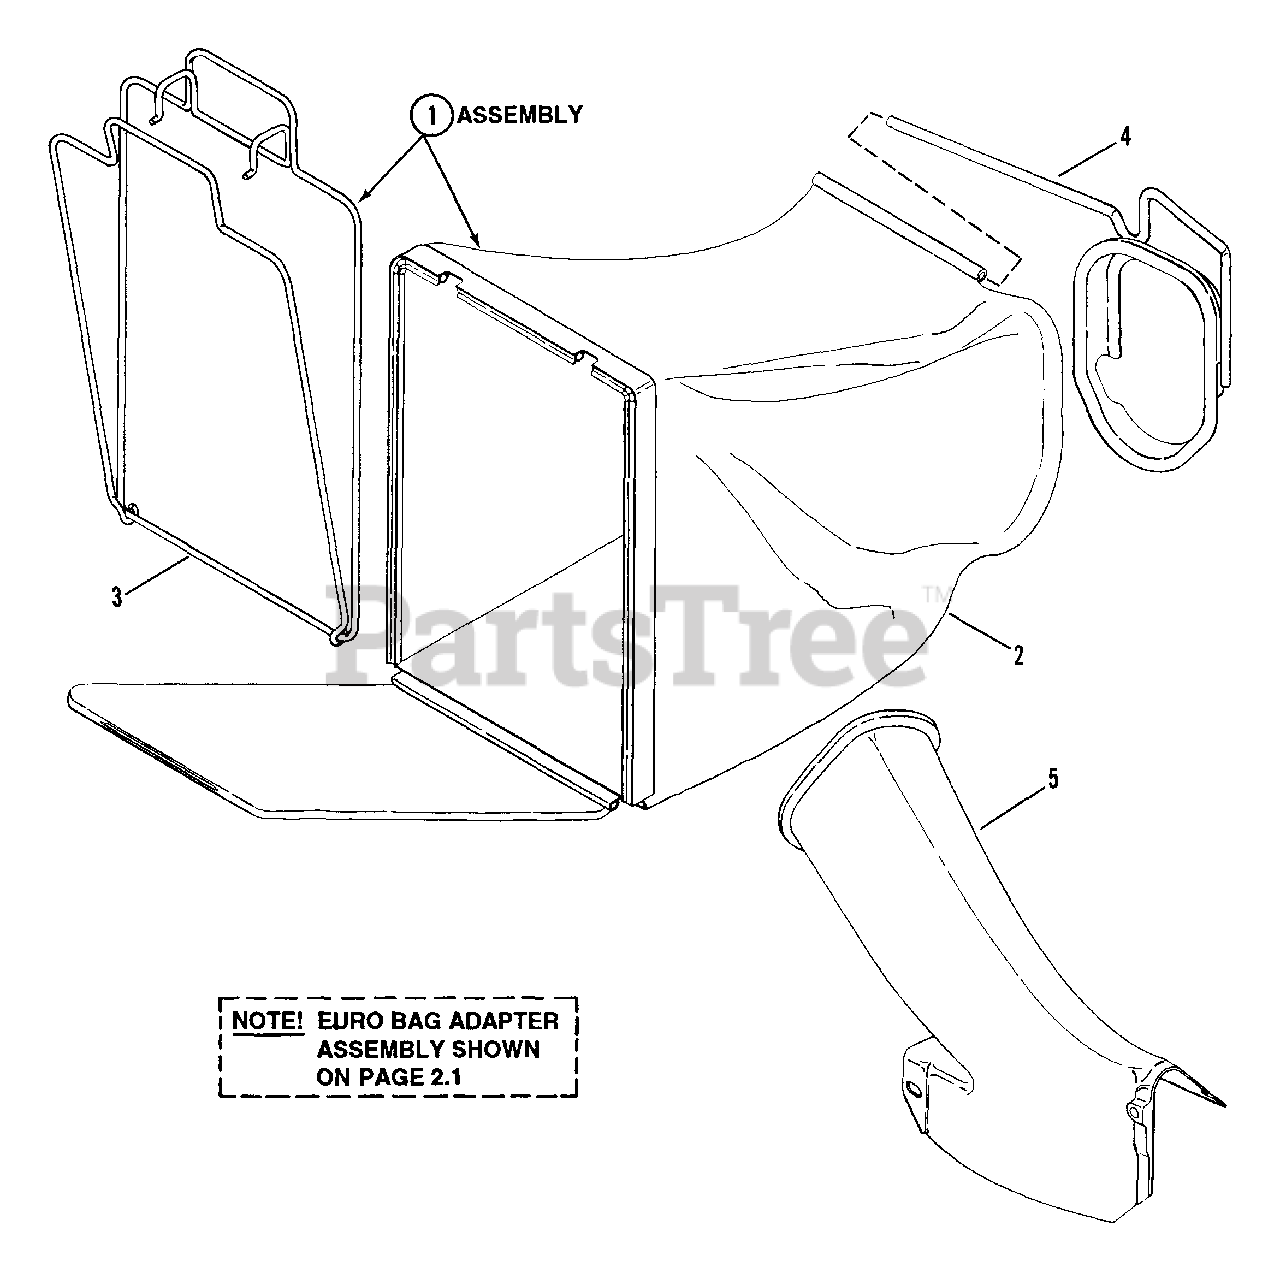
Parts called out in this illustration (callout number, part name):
1	ASSEMBLY, Grass Bag
2	BAG, Goor Type (Charcoal color)
3	ASSEMBLY, Bag Wire
4	CONNECTOR, Grass Bag
5	ADAPTER, Bag
